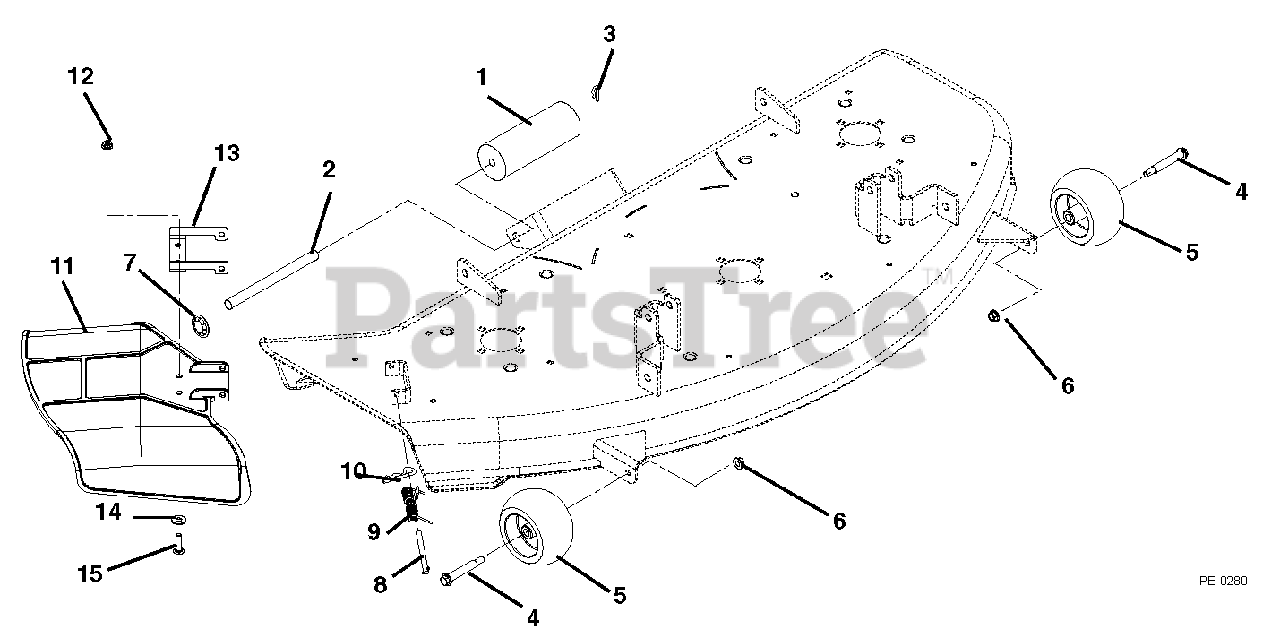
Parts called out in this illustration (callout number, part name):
1	Roller (104, 132)
2	Pin, Roller (104, 132)
3	Pin, Spring Clip (104, 132)
4	Bolt, Shoulder .38-16 x 2.50 Hex Washer Head Grade 5
5	Wheel 5 x 3
6	Nut, Locking-Top-Flange .38-16
7	Push Nut, .625 Shaft (104, 132)
8	Clevis Pin
9	Spring, Torsion
10	Pin, Hair .08 x .18 x 1.18
11	Plastic Chute
12	Nut, Locking, Top Flange .31-18
13	Chute Reinforcement
14	Washer, Flat Steel .38 x .875 x .083
15	Screw, Socket Head, Button Head .31-18 x .75
